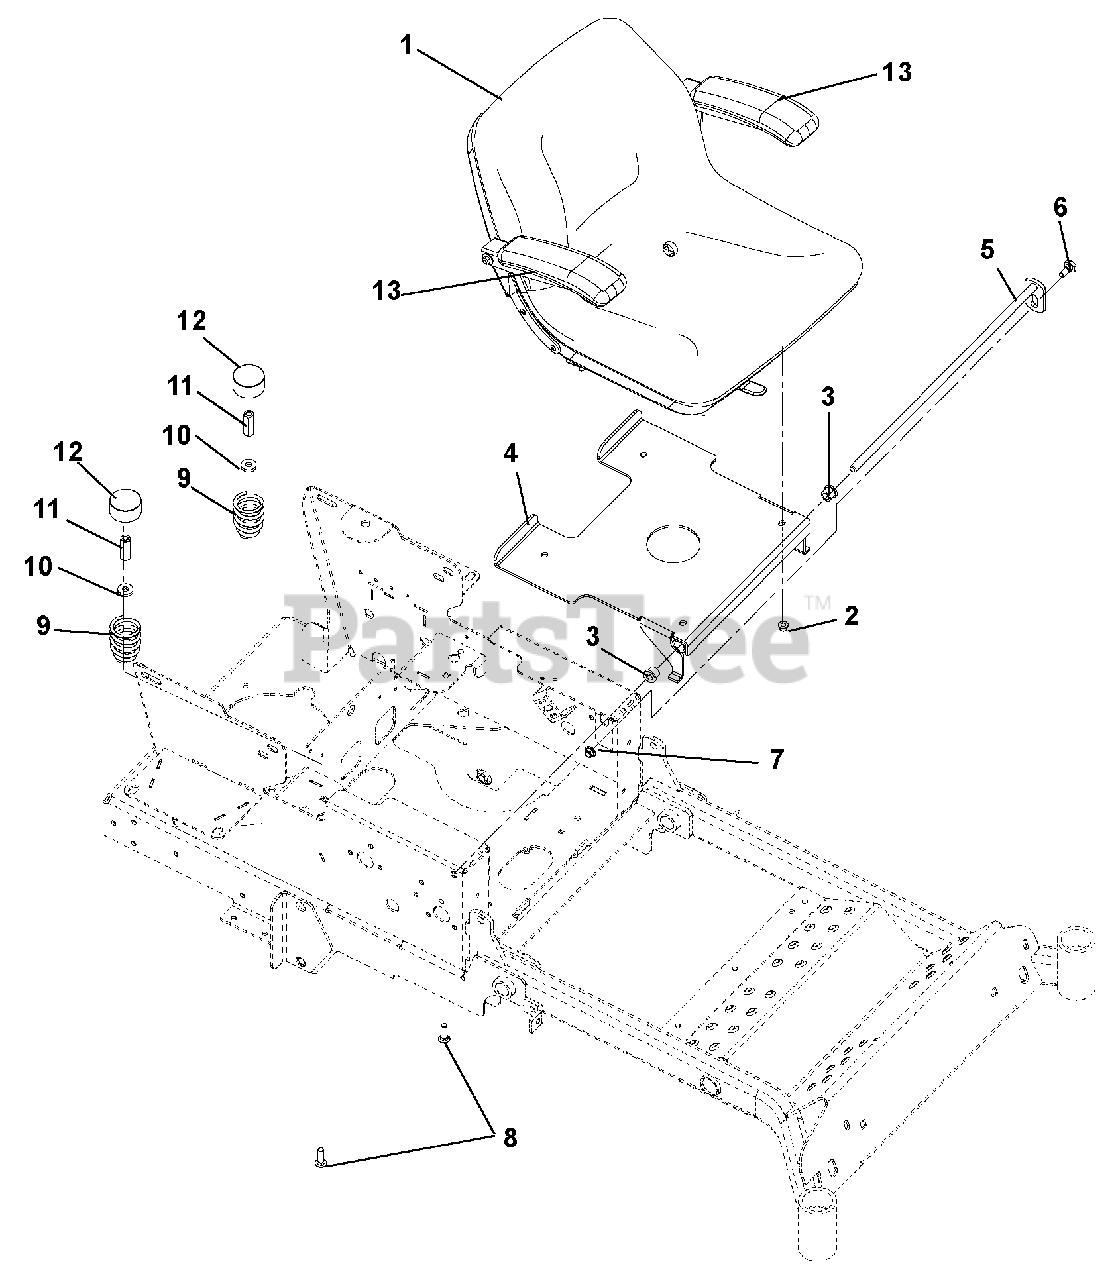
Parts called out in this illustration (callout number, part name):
1	Assembly, Seat with Armrests
2	Nut, Nyloc Flange 5/16-18
3	Bushing, Flange .515 x .750 x .745 x 1.00
4	Weldment, Seat Plate
5	Weldment, Seat Shaft
6	Bolt, Shoulder EP .38-16 x .30 Hex
7	Nut, .38-16 Nyloc Flange
8	Bolt, Round Head Square Neck .38-16 x 1.25 Grade 5
9	Spring, Seat
10	Washer, Flat Steel .406 x 1.00 x .188
11	Nut, Coupling .375-16 x 1.75
13	Kit, Seat Arm Rests
